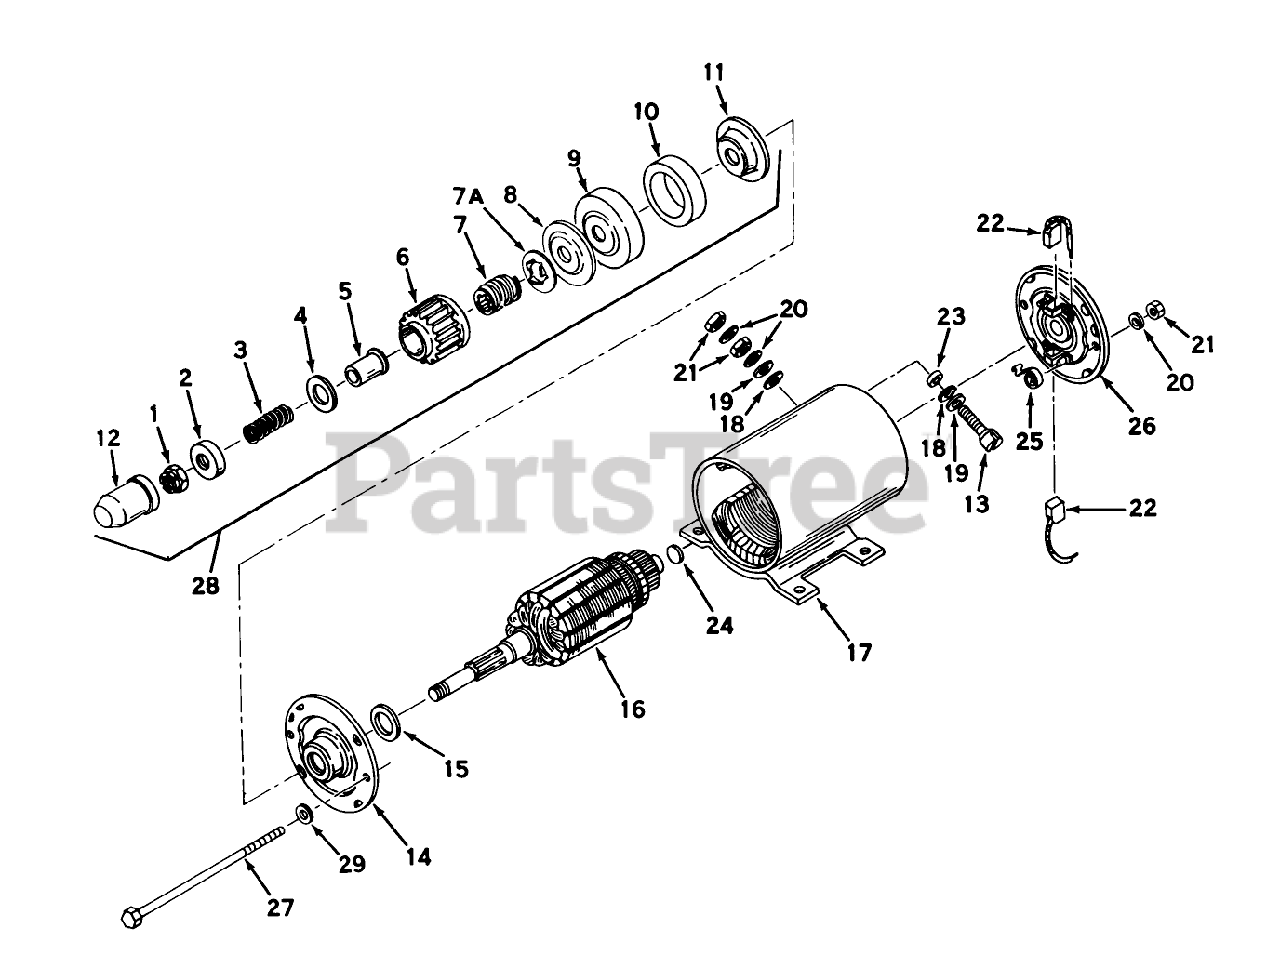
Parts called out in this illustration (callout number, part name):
1	Nut, Hex
2	Setscrew
3	Spring, Anti-Drift
4	Washer, Pinion
5	Sleeve, Anti drift
6	Gear, Pinion
7	Shaft, Screw
7A	Stopper, Screw
8	Washer, Thrust
9	Cap, Cushion
10	Cushion, Rubber
11	Washer, Thrust
13	Bolt, Terminal
14	Cap Assy., Drive end (Incl. Bearing)
15	Washer, Spacing (.024 Thick)
15	Washer, Spacing (.008 Thick)
16	Armature
17	Housing Assy. (Incl. pole shoes, field coils, terminal post, straight mounting bracket, Nos. 18 thru 21)
18	Washer, Insulating
19	Washer
20	Washer, Lock
21	61710/VAR.HILLER AT
22	Brush Spring Kit
23	Bushing, Insulating
24	Washer, Spring
25	Spring, Brush
26	End Cap Assy., Commutator
27	Bolt, Thru
28	Drive Assy., Complete (Incl. Nos. 1 thru 12)
29	Washer
